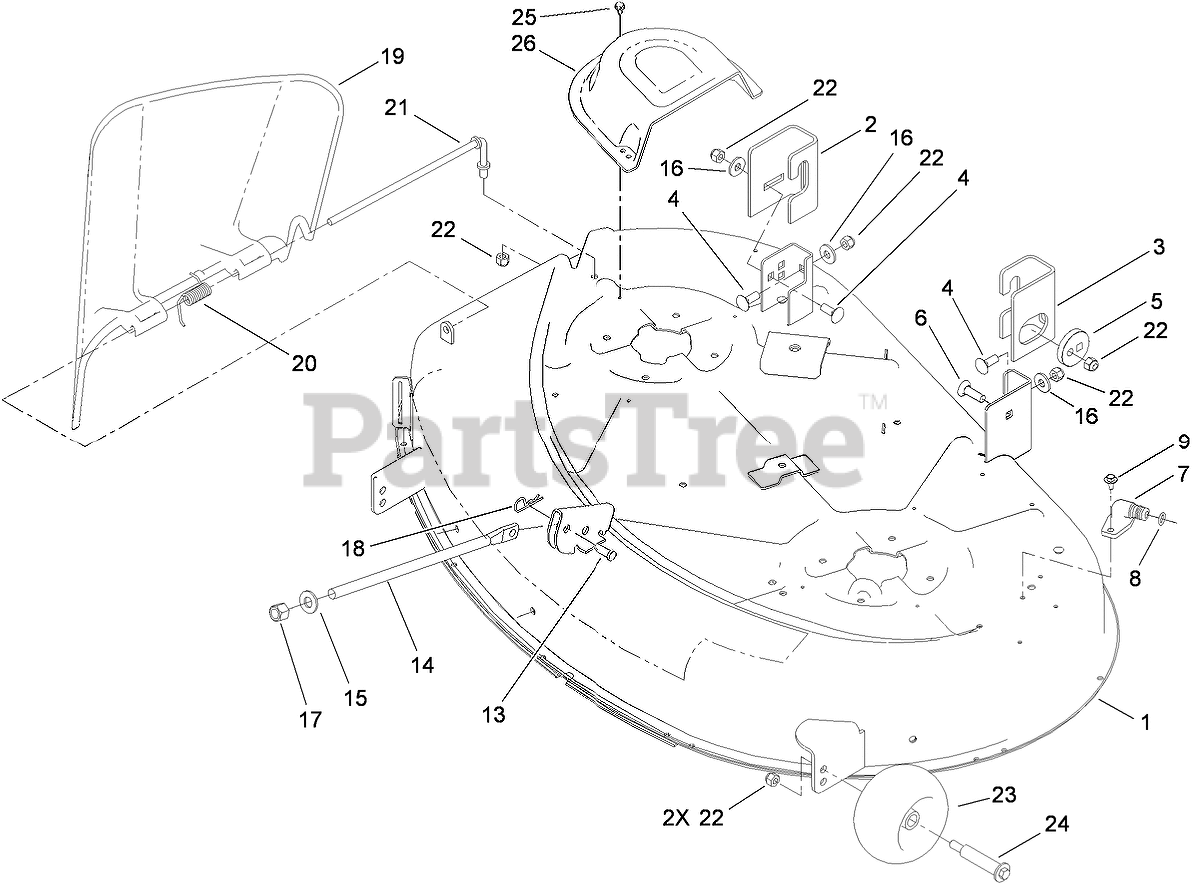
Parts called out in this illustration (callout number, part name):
1	42 INCH DECK AND DECAL ASM
2	BRACKET-HANGER, RIGHT REAR
3	BRACKET-HANGER, LEFT REAR
4	BOLT-CARR
5	ECCENTRIC
6	SCREW-CARR
7	FITTING-WASHOUT
8	O-RING
9	SCREW-HHFTF
13	PIN-CLEVIS
14	ROD-LIFT
15	WASHER-THRUST
16	WASHER-HARDENED
17	NUT-LOCK, NI
18	PIN-HAIR
19	DEFLECTOR
20	SPRING-TORSION
21	ROD-PIVOT
22	NUT-LOCK, NI
23	ROLLER-SCALP, ANTI
24	BOLT-SHOULDER
25	SCREW-HWHTF
26	COVER-BELT
